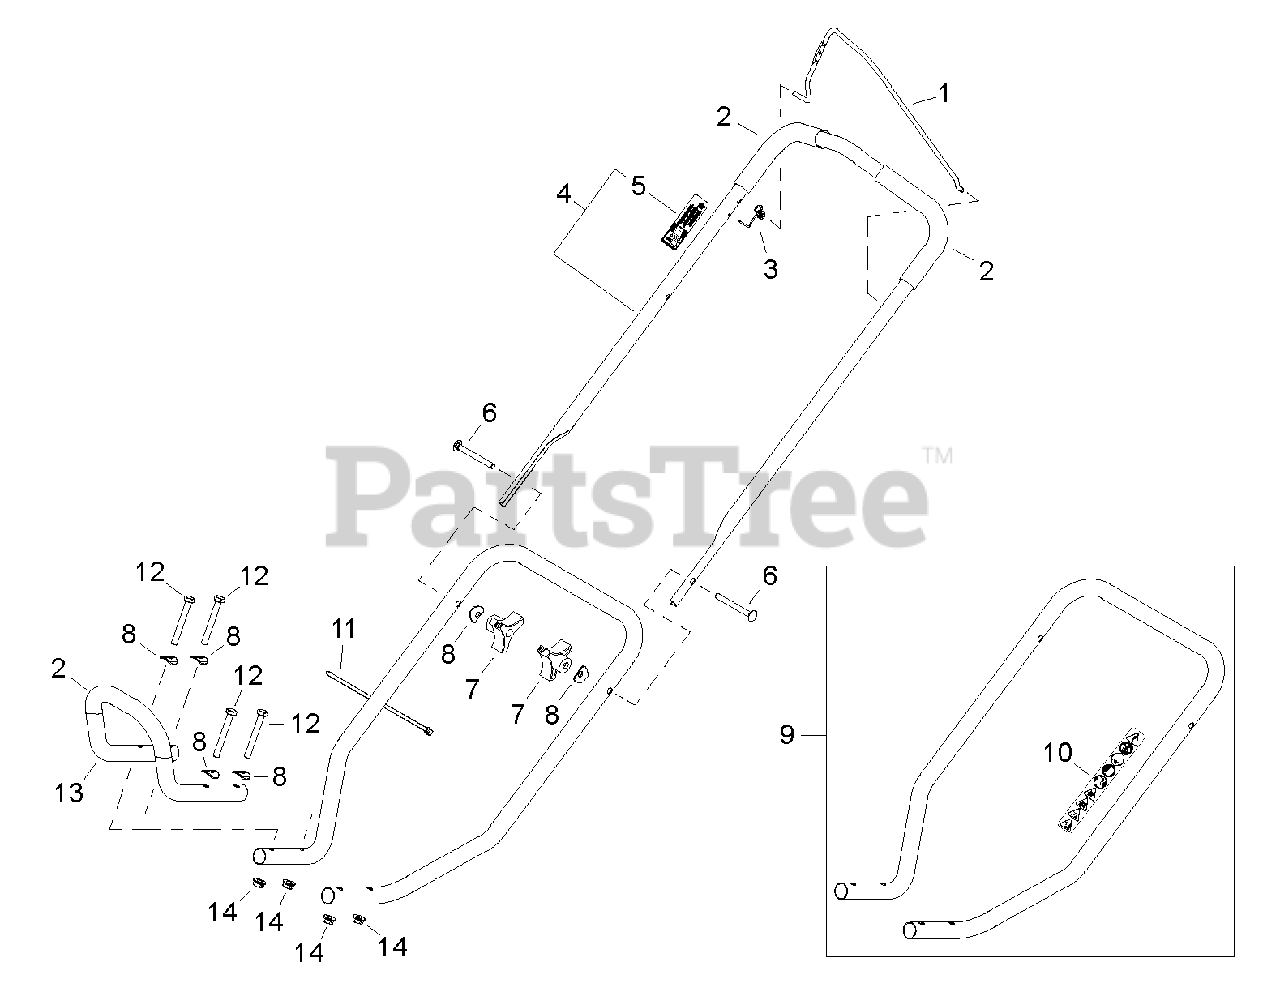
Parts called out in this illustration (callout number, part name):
1	CONTROL, BAIL THROTTLE
2	GRIP, FOAM
3	SPRING, TORSION
4	HANDLE ASSY, UPPER
5	LABEL, IGNITION SWITCH
6	BOLT
7	KNOB
8	WASHER, SHOULDER
9	HANDLE ASSY, LOWER
10	LABEL, CAUTION
11	TIE, CABLE
12	SCREW
13	HANDLE, FRONT
14	NUT, LOCK
